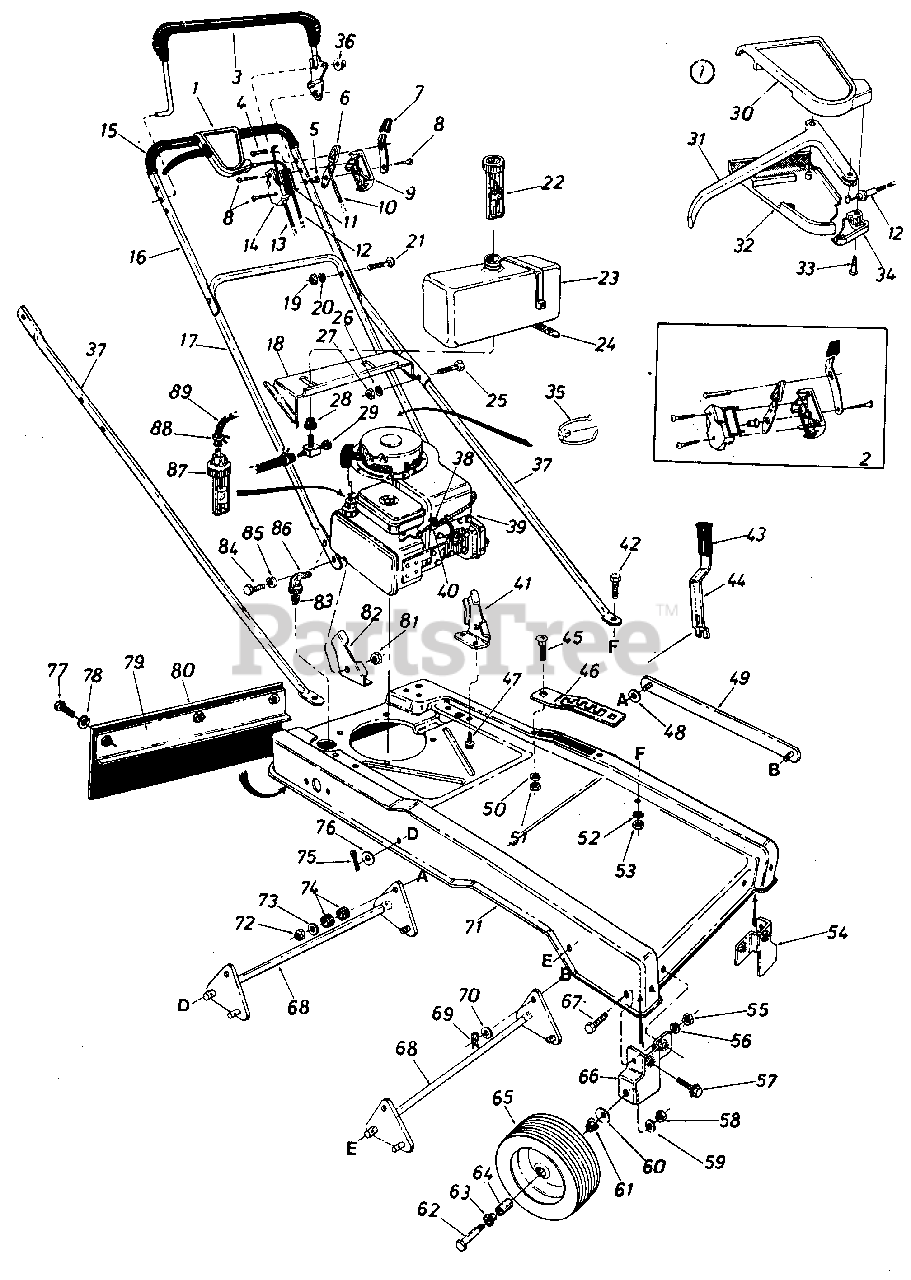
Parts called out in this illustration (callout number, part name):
1	Clutch Control Housing Comp.
2	Control Housing Comp.
3	Control Handle Ass'y.
5	Control Disc Pin
6	Throttle Control Lever
7	Spring Lever Knob
8	Truss Mach. Hi-B Tap Scr. #12 x 1.50" Lg.
9	Control Panel Half
10	Throttle Control Wire 43" Lg.-Yellow
11	Control Label Throttle
12	Drive Clutch Cable 46" Lg.
13	Self-Propelled Cable 50" Lg.
14	Clutch Panel Half
15	Grip 22" Lg.
16	Upper Handle
17	Lower Handle
18	Gas Tank Mounting Brk't.
19	Hex Nut 5/16-18 Thd.
20	L-Wash. 5/16" I.D.*
21	Carriage Bolt 5/16-18 x 1.50" Lg.*
22	Gas Gauge 1-3/4-6 x 5.50" Lg.
24	Cable Tie 30.6" Lg.
25	Hex Bolt 5/16-24 x 1.25" Lg.*
26	L-Wash. 5/16" I.D.
27	Hex Nut 5/16-24 Thd.
28	Bushing Gas Tank
29	Fuel Shut-Off Valve w/ Screen
30	Control Cover Half Upper
31	Control Lever
32	Control Cover Half Lower
33	Flat "C" Sunk Hd. Tap Scr. #10 x .75" Lg.
34	Cable Mounting Cap
35	Cable Tie
37	Strut .75" O.D. x 43.44" Lg.
38	Hex Sems Scr. #10-32 x .62" Lg.
39	Engine 5 H.P.
40	Casing Clamp
41	Handle Mount Brk't. L.H.
42	Hex Bolt 5/16-18 x .75" Lg.
44	Lift Handle
45	Carriage Bolt 5/16-18 x .62" Lg.*
46	Lift Handle Support Brk't.
47	Hex Wash. Hd. B-Tap Scr. 5/16-18 x .50
48	Fl-Wash. .406" I.D. x 1.25" O.D.
49	Connecting Link Ass'y.
50	L-Wash. 5/16" I.D.
51	Hex Nut 5/16-18 Thd.
52	L-Wash. 5/16" I.D.
53	Hex Nut 5/16-18 Thd.*
54	Wheel Brk't. Ass'y. L.H.
55	Hex Nut 5/16-18 Thd.
56	L-Wash. 5/16" I.D.*
57	Hex Sems Bolt 5/16-18 x .75" Lg.
58	Hex Cent. L-Nut 3/8-16 Thd.
59	L-Wash. 3/8" I.D.*
60	Bell-Wash. .400" I.D. x .88" O.D.
61	Flange Ball Brg. .501" I.D.
62	Hex Bolt 3/8-16 x 2.00" Lg.
63	Flanged Ball Brg. 3/8" I.D.
64	Spacer .375" I.D. x .505" O.D. x 1" Lg.
65	Wheel Ass'y. Comp. 8 x 1.75
66	Wheel Brk't. Ass'y. R.H.
67	Hex Sems Bolt 5/16-18 x .75" Lg.
68	Lift Brk't. Shaft Ass'y.
69	Intern. Cotter Pin 5/16" Dia.
70	Fl-Wash. .385" I.D. x .88" O.D.
71	Hi-Wheel Frame
72	Hex Ins. L-Nut 3/8-24 Thd.
73	Fl-Wash. .385" I.D. x .87" O.D.
74	Rubber Wash. .33" I.D. x .87" O.D.
75	Cotter Pin 1/8" Dia. x 1" Lg.*
76	Fl-Wash. .510" I.D. x 1.0" O.D.
77	Hex Bolt 1/4-20 X .62" Lg.
78	L-Wash. 1/4" I.D.*
79	Retaining Strip Ass'y. 2" x 15" Lg.
80	Rear Flap 7.5 x 20" Lg.
81	Hex Nut 3/8-16 Thd.
82	Handle Mount Brk't.
83	Part of Engine
84	Hex Bolt 3/8-16 x .75" Lg.
85	L-Wash. 3/8" I.D.*
86	90 Deg. Elbow Male to Female 3/8
87	Fuel Control Valve
88	Hose Clamp .406" Dia.
89	Fuel Line 13" Lg.
